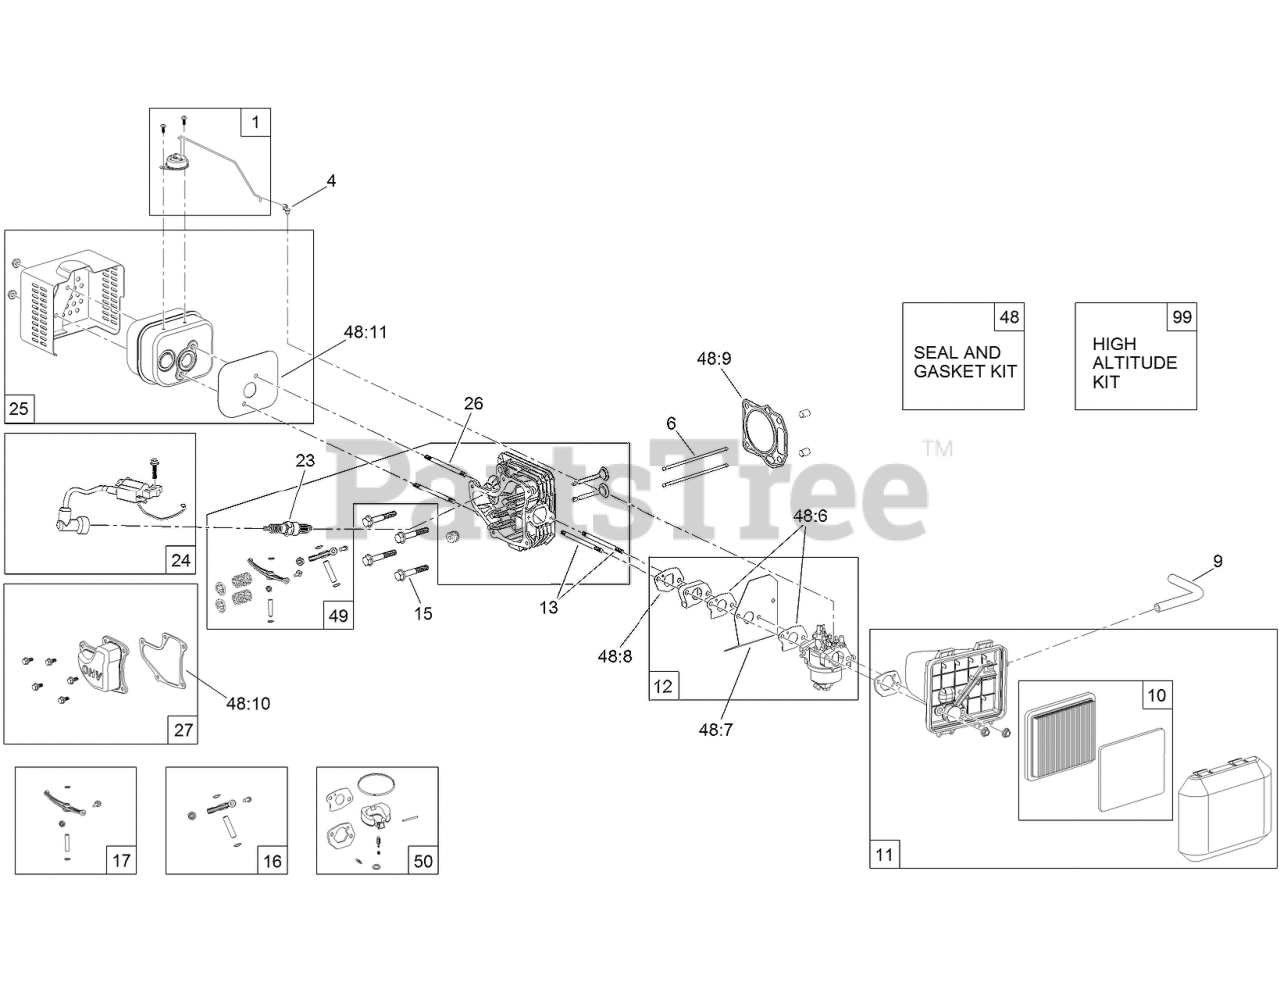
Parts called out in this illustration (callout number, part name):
1	THERMAL CONTROL KIT
4	LOCK-THROTTLE
6	ROD-PUSH
9	TUBE-BREATHER
10	AIR FILTER AND PREFILTER KIT
11	AIR CLEANER ASM KIT
12	CARB REPLACEMENT KIT
13	STUD-INTAKE
15	BOLT-FLANGE
16	INTAKE ROCKER ARM ASM
17	EXHAUST ROCKER ARM ASM
23	SPARK PLUG
24	IGNITION ASM
25	MUFFLER AND SHIELD KIT
26	STUD-EXHAUST
27	VALVE COVER KIT
48	SEAL AND GASKET KIT
48:6	GASKET-CARBURETOR
48:7	INSULATOR-CARBURETOR
48:8	GASKET-INTAKE
48:9	GASKET-HEAD
48:10	GASKET-VALVE COVER
48:11	GASKET-EXHAUST
49	COMPLETE HEAD ASM
50	INTERNAL CARB KIT WITH GASKETS
99	HIGH ALTITUDE KIT
